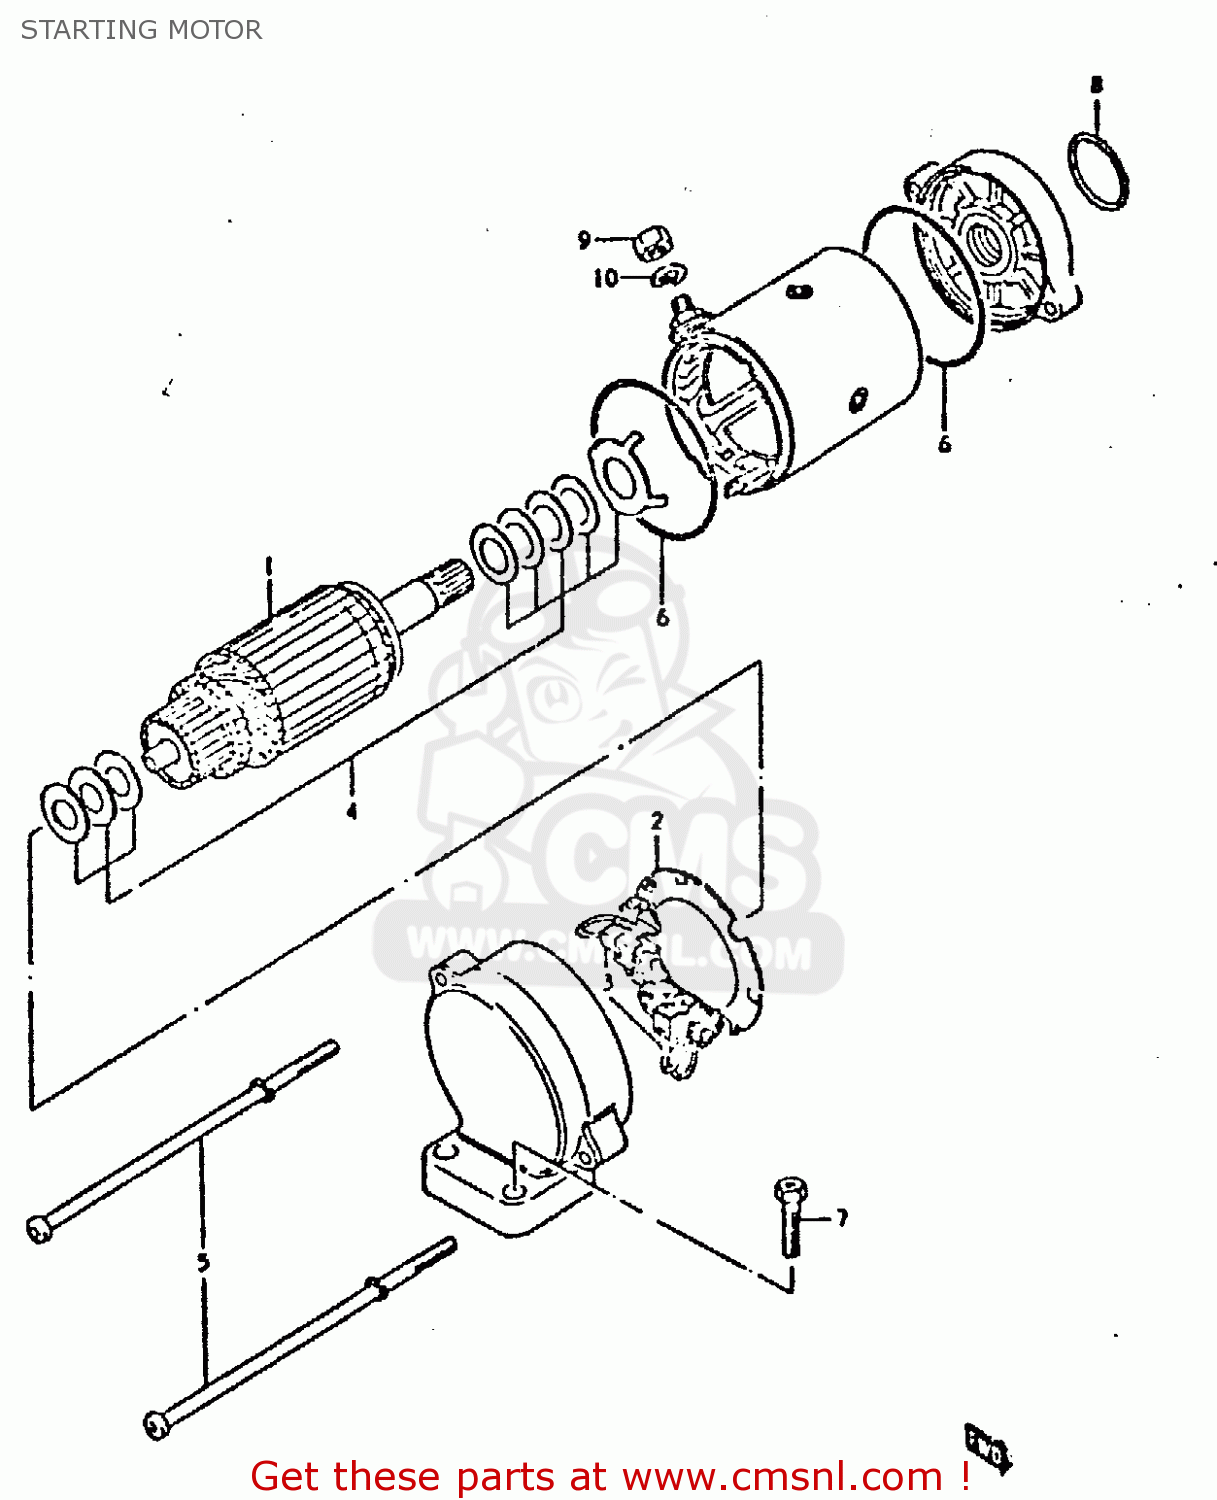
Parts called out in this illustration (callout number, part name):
1	ARMATURE
2	HOLDER ASSY
3	BRUSH SET
4	SHIM SET
5	BOLT,STARTING MOTOR HOUSING
6	O RING
7	SCREW (6X25)
8	O RING(D:2,ID:24.5)
9	NUT 6MM
10	LOCK WASHER
